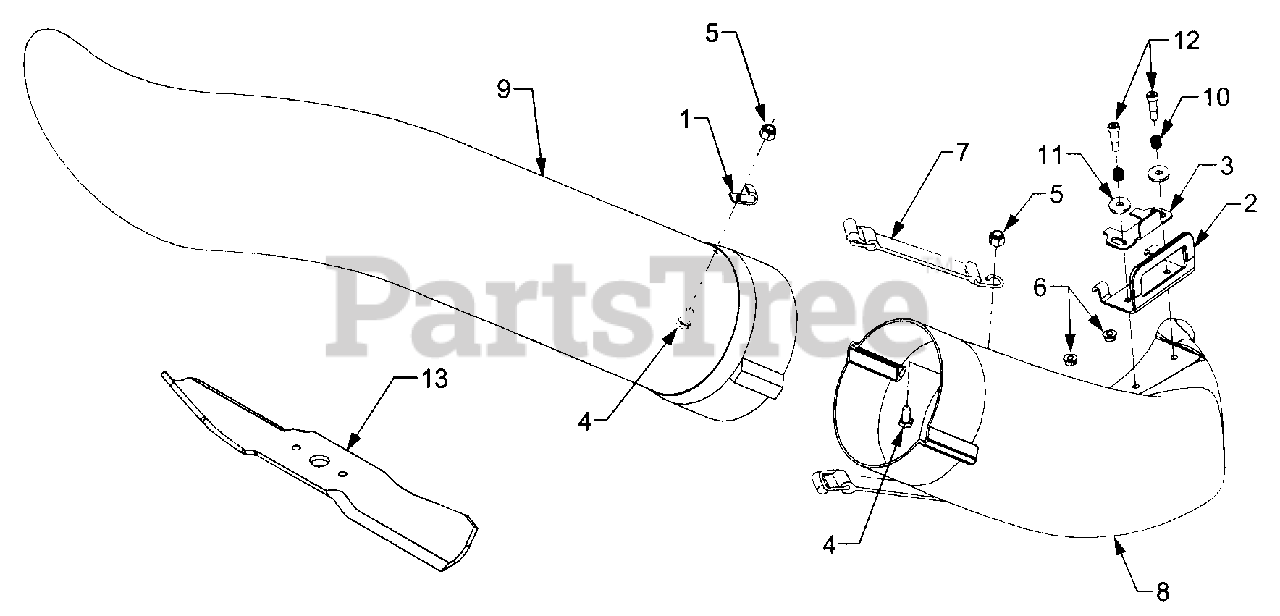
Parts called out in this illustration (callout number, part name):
1	Bracket, Retainer Hook
2	Bracket, Chute
3	Latch, Chute
4	Screw, Hex Cap, 1/4-20 x .62 GR5
5	Nut, Hex Insert Lock, 1/4-20
6	Nut, Hex Flange Lock, 5/16-18
7	Strap Assembly, Retainer
8	Chute, Discharge
9	Tube, Chute
10	Spring, Compression, .5 x .5 Lg.
11	Washer, Flat, 3/8 x 1.25
12	Screw, Shoulder 3/8 x .625 : 5/16-18
13	Blade, High Lift
